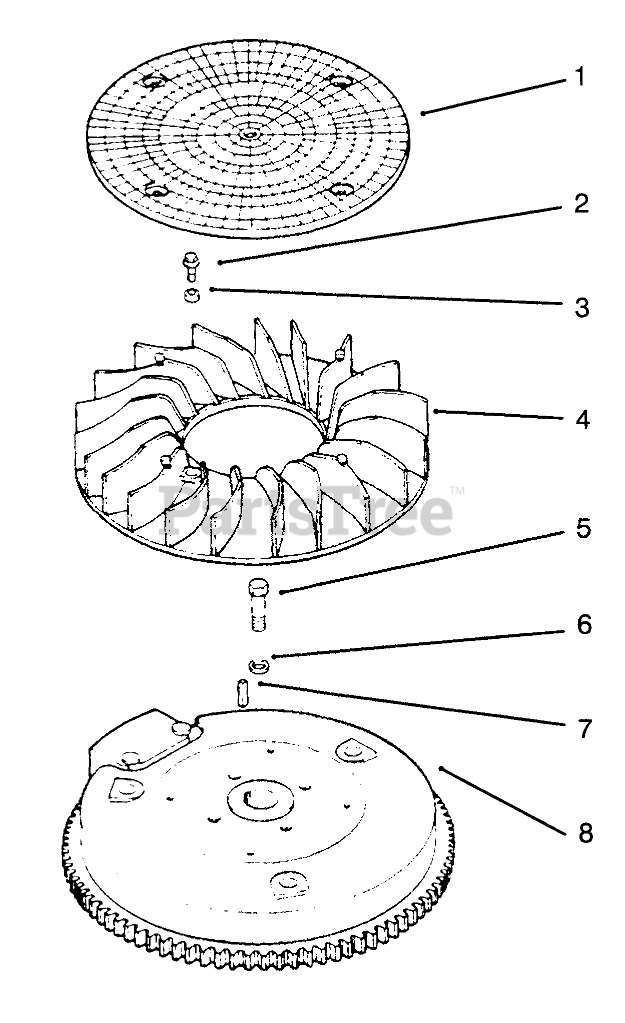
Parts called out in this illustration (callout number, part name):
1	Screen-Grass
2	Screw-HexWash. Hd.
3	Spacer
4	Fan
5	Screw-Hex. Hd.
6	Washer-Flat
7	Key
8	Flywheel
